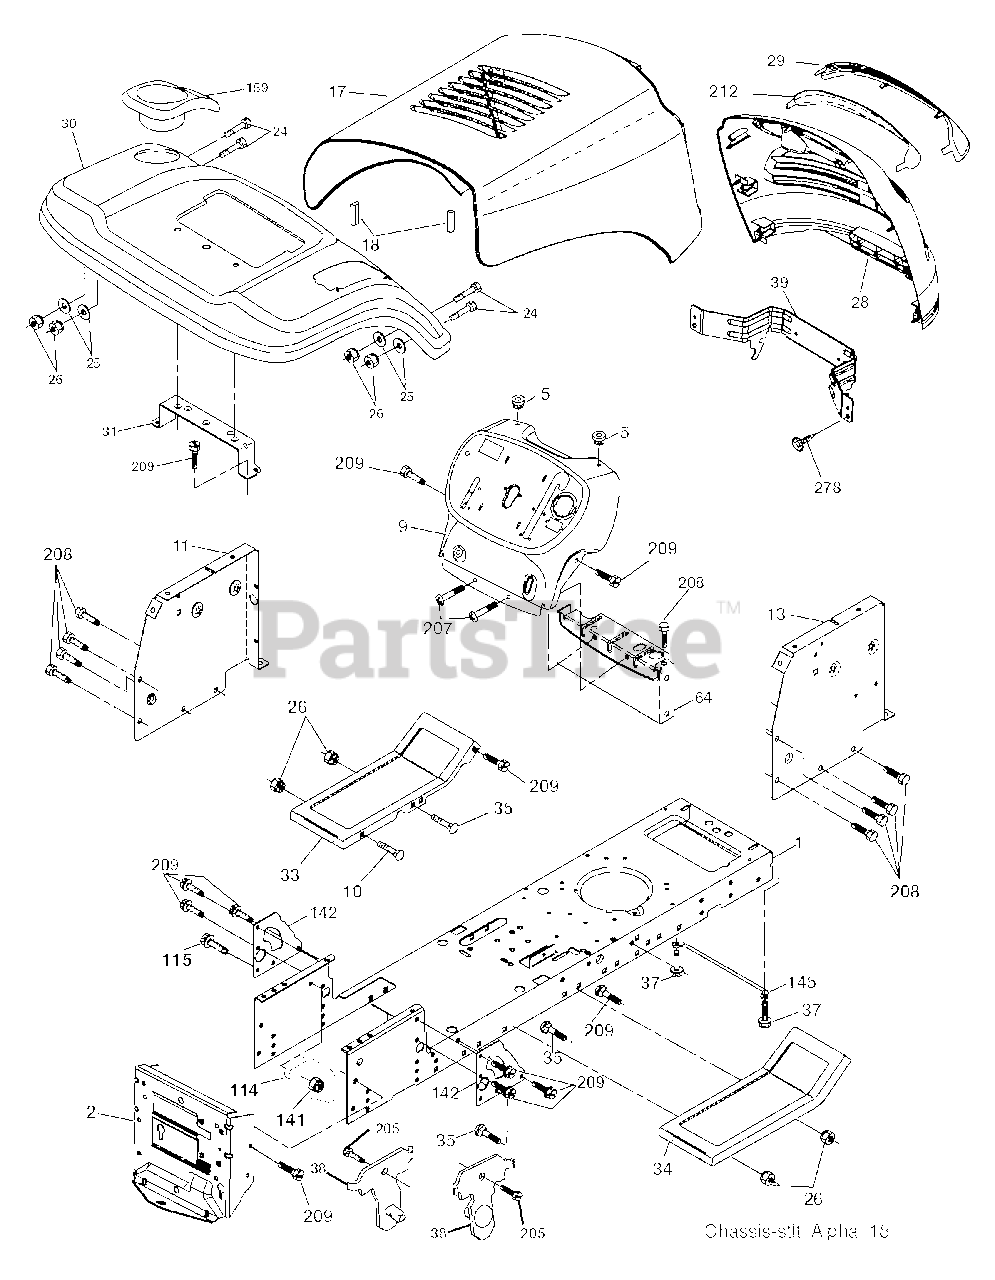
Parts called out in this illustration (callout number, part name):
1	CHASSIS STAMPING
2	DRAWBAR, 12GA
5	BUMPER.RUBBER.HOOD
11	PANEL DASH LH
13	PANEL SLKSCR DASH RH
17	HOOD.BLACK.ALPHA
18	BUMPER.HOOD.LARGE.1.75"
25	WASHER
26	NUT
28	GRILLE.ASM.ALPHA
29	LENS.ALPHA.BAR.LT
30	FENDER.LTST.W/SHFT.CUP.BLACK
31	BRACKET FENDER
33	FOOTREST.LH.BLACK
34	FOOTREST.RH.BLACK
37	SCREW LT
38	BRACKET.ASM.PIVOT.MOWER.REAR
39	BRACKET.PIVOT.ALPHA.LT
64	DASH LOWER
115	SCREW.3/8-16
141	NUT LOCK FLG 3/8-16 UNC
142	PLATE REINFORCEMENT
145	ROD.PIVOT.HOOD
159	CUPHOLDER.BLACK
205	SCREW LT
207	SCREW, 5/16-18 X 1/2
208	SCREW 3/8-16X1/2
209	SCREW, 3/8-16X3/4
212	INSERT.ALPHA.REFLECTIVE.LT.
278	SCREW.#10 X 0.750.BOS (2 2)
